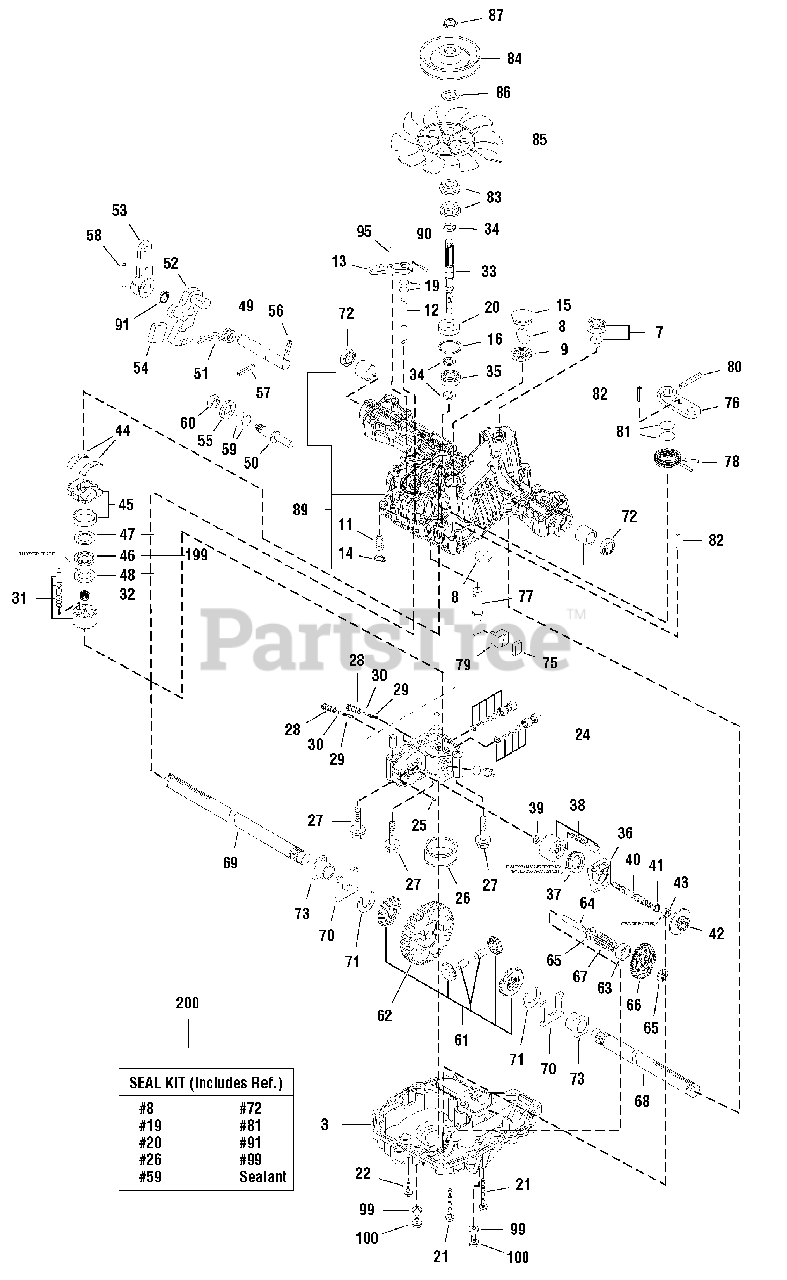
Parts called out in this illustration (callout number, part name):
3	*LOWER HOUSING
7	VENT VALVE 15
9	*HOLDER MAGNET
12	SHAFT (BYPASS)
13	LEVER BYPASS
15	SEALING CAP 30
16	RING, Snap, C 35
19	O-RING, 1A P10A
20	SEAL TC 153507
21	SCREW, Tapping, 8*30
24	CENTER CASE E CMP
26	FILTER K50 SNP
31	CYLINDER BLOCK
32	SPRING (PUMP)
34	RING E 15
35	BEARING 6202C3
37	BEARING 51106
38	*CYLINDER BLOCK
39	WASHER 12*24*1
40	SHAFT MOTOR
41	RING, SNAP S 15
43	BEARING 6202C3U
44	THRUST METAL
45	SWASH PLATE CMP.
46	BEARING K81105
47	THRUST PLATE B
48	THRUST PLATE A
49	*CONTROL SHAFT
50	*FULCRUM (ECCENTRICIT
51	SP (TORSION
52	CONTROL ARM E
53	CONTROL LEVER
54	JERKY PLATE
56	SPRING PIN 6.0A*36
58	PIN, ROLL 6*40
59	O-RING 1A P14
61	DIFF PINION
62	*FINAL GEAR
63	*COLLAR, FINAL P
64	*REDUCTION SHAFT
66	REDUCTION GEAR
67	*FINAL PINION
68	AXLE SHAFT L
69	AXLE SHAFT R
70	THRUST WASHER
72	SEAL 19*32*8
77	*SHAFT BRAKE
78	RETURN SPRING B
79	ACTUATOR BRAKE
81	O-RING 1A P12
82	PIN SPRING 4*16
83	SPLINE COLLAR
85	FAN
86	LOCK WASHER
89	*UPPER HOUSING
90	SPRING PIN 3*16
91	OIL SEAL 16*22*03
95	PIN 3.0A*20
99	WASHER, SEAL 8
199	*BEARING
200	SEAL KIT, K46 (All Models)
201	*KIT, Repair
